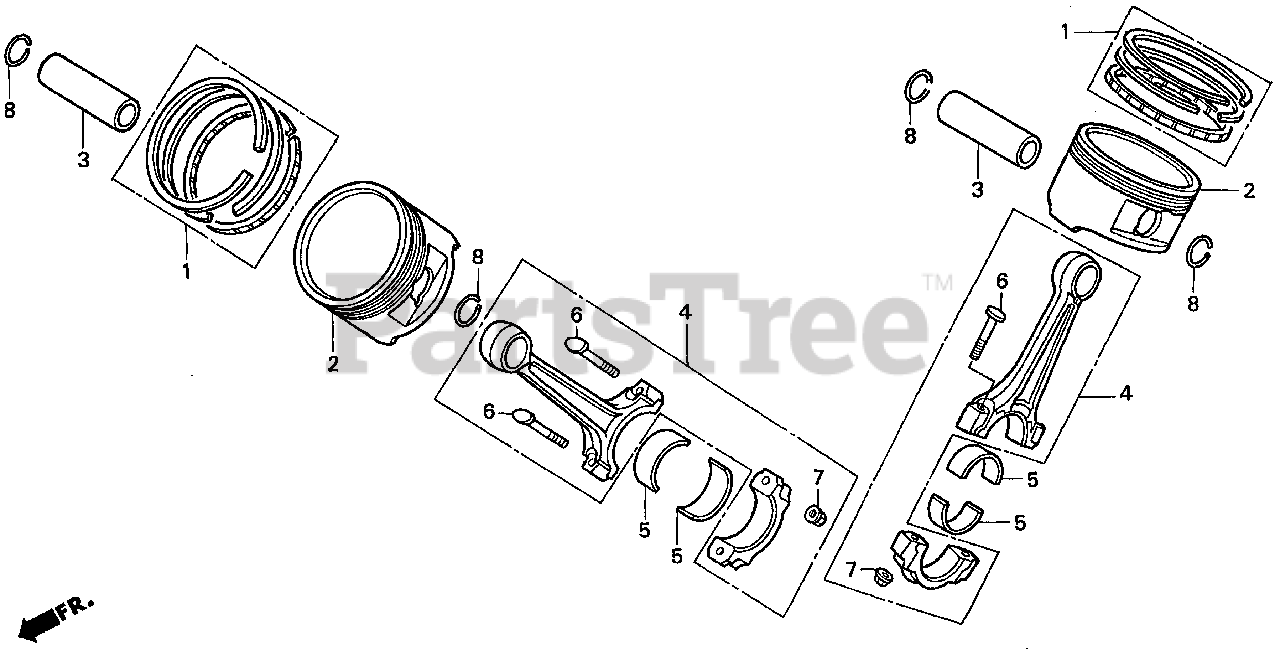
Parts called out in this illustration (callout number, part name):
1	RING SET, PISTON (STD)
1	RING SET, PISTON (OS 0.25)
1	RING SET, PISTON (OS 0.50)
1	RING SET, PISTON (0.75)
2	PISTON
2	PISTON (OS 0.25)
2	PISTON (OS 0.50)
2	PISTON (0.75)
3	PIN, PISTON
4	ROD SET, CONNECTING
5	BEARING A, CONNECTING ROD (BLUE)
5	BEARING B, CONNECTING ROD (BLACK)
5	BEARING C, CONNECTING ROD (BROWN)
5	BEARING D, CONNECTING ROD (GREEN)
5	BEARING E, CONNECTING ROD (YELLOW)
5	BEARING F, CONNECTING ROD (PINK)
5	BEARING G, CONNECTING ROD (RED)
6	BOLT, CONNECTING ROD
7	NUT, CONNECTING ROD
8	CLIP, PISTON PIN (18MM)
